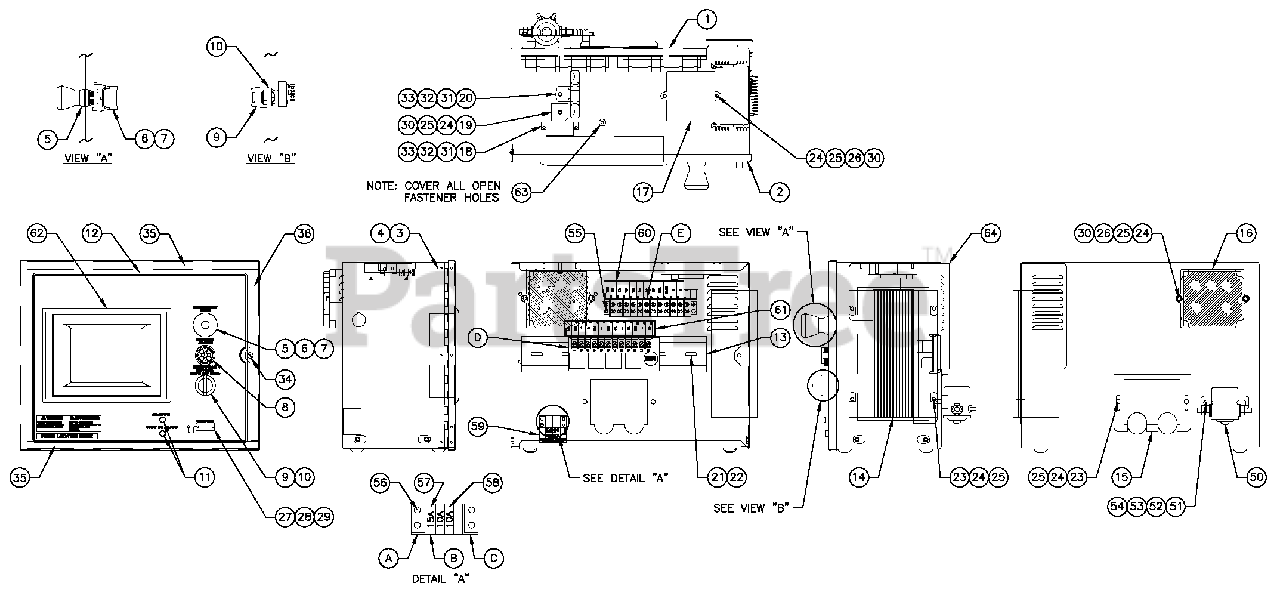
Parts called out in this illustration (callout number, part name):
1	ENCLH/G CONTROL PANEL
2	COVER CONTROL PANEL
3	HINGE CONTINUOUS H PANEL
4	RIVET POP .125 X .275 SS
5	SWITCH E-STOP
6	CONTACT BLOCK NC
7	CONTACT BLOCK NO
8	PIEZO BUZZER PANEL MNT
9	KEY SWITCH ON-OFF-ON MAINTAIN
10	KEY SWITCH SPACER FOR HOBBS
11	PILOT LIGHT 8MM RED LED
12	DECAL CONTROLG
13	RAIL SNAPTRACK PCB HOLDER BULK
14	ASSY PCB 10A UL BATT CHRGR12V
15	PLATE HARNESS CLAMP
16	ASSY PCB PWR AVR W/AMP HEADER
17	ASSY PCB BOSCH GOV DRIVER
18	CB5.5AX 1P AUTO
19	DIO B RIDGE 25A 600V
20	RES WW 25R 5% 25W QK CONN
21	SCREW PHTT M4-0.7 X 10 ZYC
22	WASHER FLAT M4
23	SCREW HHPMM5-0.8X12
24	WASHER FLAT M5
25	WASHER LOCK M5
26	SCREWPPHM M5-0.8 X 30 SS
27	CONN DUST CAP W/CHAIN DB9
28	SCREW PHTT M3.5-0.6X 10
29	WASHER FLAT M 35
30	NUTHEX M5-0.8G8 CLEARZINC
31	WASHER LOCK M3
32	WASHER FLAT M3
33	NUTHEX M3-0.5G8YEL CHR
34	M5-0.8 CAPTIVE PANEL KNLD HD
35	SEAL COVER 3.18X12.7X382
36	SEAL COVER 3.18X12.7X283
50	RELAY SOLENOID 12VDC PNLMNT
51	SCREW HHC 1/4-20 X 3/4 G5
52	WASHER FLAT 1/4-M6 ZINC
53	WASHER LOCK M6-1/4
54	NUT HEX 1/4-20 STEEL
55	SCREW PHTT #6-32 X 5/8 ZYC
56	SCREW PHTT #6-32 X 3/8 ZYC
57	FUSE ATOTYPE15 AMP (BLUE)
58	FUSE ATOTYPE 10 AMP (RED)
59	DECAL CPL CONTROL PANEL FUSES
60	DECAL 24VDCTB3
61	DECAL H-100 RELAY BRD24V RB2
62	TOUCH PANEL CONFIG GEN MQT
63	SEAL WEATHER .45"DIA
64	COVER CONTROL PANEL SIDE
A	ADPTR RH SIDE WICKMANN 178.6191
B	HOLDERFUSE WICKMANN 178.6150
C	ADPTR LH SIDE WICKMANN 178.6192
D	ASSY PCB G-PANEL RELAY 12VDC
E	BLOCK TERM 20A12 X 6 X1100V
